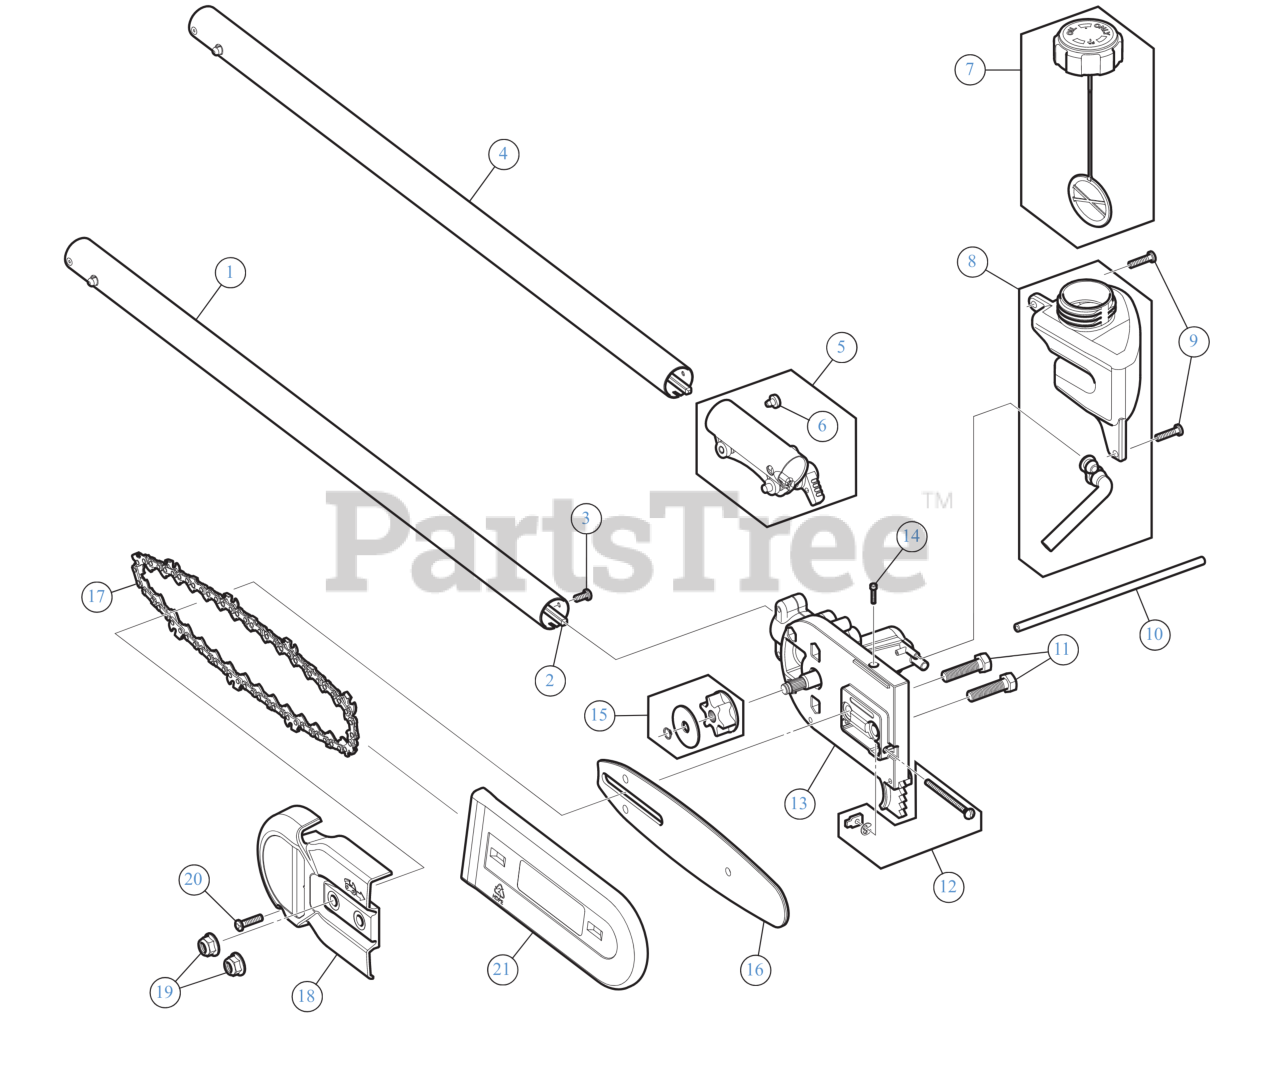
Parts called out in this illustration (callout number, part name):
1	LOWER DRIVE SHAFT HOUSING
2	FLEXIBLE DRIVE SHAFT
3	SCREW 1/4-20 X.500
4	BOOM ASSEMBLY
5	CLAMP ASM DW BK
6	SCREW, 10-32X.250 TA
7	FUEL CAP ASSEMBLY
8	OIL TANK ASSEMBLY
9	SCREW, #8-16X.750 PH
10	OIL LINE
11	SCREW 5/16-18 x 1.25 GR5
12	CHAIN TENSION HDW
13	GEAR BOX ASSEMBLY
14	SCREW 4X40X.50
15	SPROCKET ASSEMBLY
16	BAR 8" SPROCKET NOSE
17	CHAIN 8" 34 LINK .043 GAUGE
18	CHAIN GUARD
19	FLANGE LOCK NUT 5/16-18
20	SCREW, #8-16X.750 PH
21	8" SCABBARD
